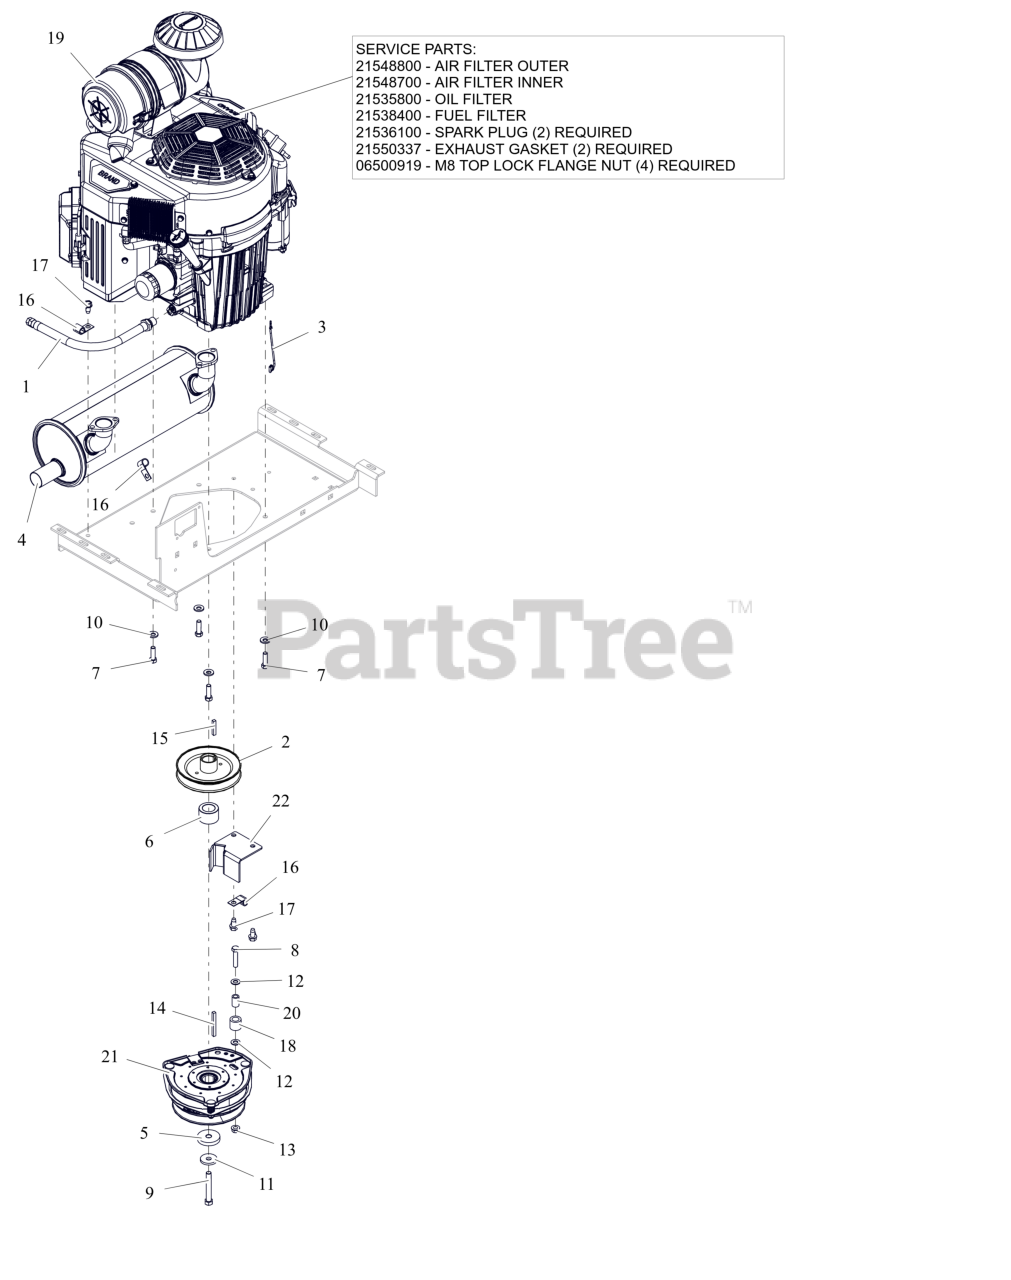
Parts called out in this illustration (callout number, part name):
1	HOSE, OIL DRAIN
2	WLDMT, TRANSAXLE DRIVE PULLEY
3	LEAD - STARTER SOLENOID
4	MUFFLER - 34HP KAWASAKI VERT.
5	SPACER, .474/.459X2.00X.350
6	SPCR, 1.125 x 1.750 x 1.147
7	BLT, HEX .38-16X1.25 G5 ZCC NT
8	BLT, HEX .38-16X1.75 G5 ZCC
9	BLT, HEX 0.4375-20X3 G8 ZCC NT
10	WASHER, 3/8" SPRING DISC
11	WASHER, 7/16" SPRING DISK
12	WSHR,FLT .406X.812X.065 ZCC
13	NUT-LK-CTR-FLG .375-16 GF ZCC
14	KEY-SQ .25 X 2.50 X .25 SAE
15	KEY-SQ .25 X 1.50 X .25 SAE
17	SCR,TAP .375-16X.75 HWH TR ZCC
18	BUMPER,RUBBER .62X1.0X.88 LG
19	ENGINE-KAWASAKI FX921
19	FILTER, OUTER
19	FILTER, INNER - KAW
19	FILTER,OIL - KAW
19	FUEL FILTER - KAWASAKI
19	PLUG, SPARK
19	GASKET, EXHAUST (11061-7061)
19	NUT-LK-TOP-FLG M8 ZCC
20	BUSH.,S.391X.622X.950 ST
21	CLUTCH, OGURA GT3.5-AR04
22	WLDMT, CLUTCH STOP (BLACK)
